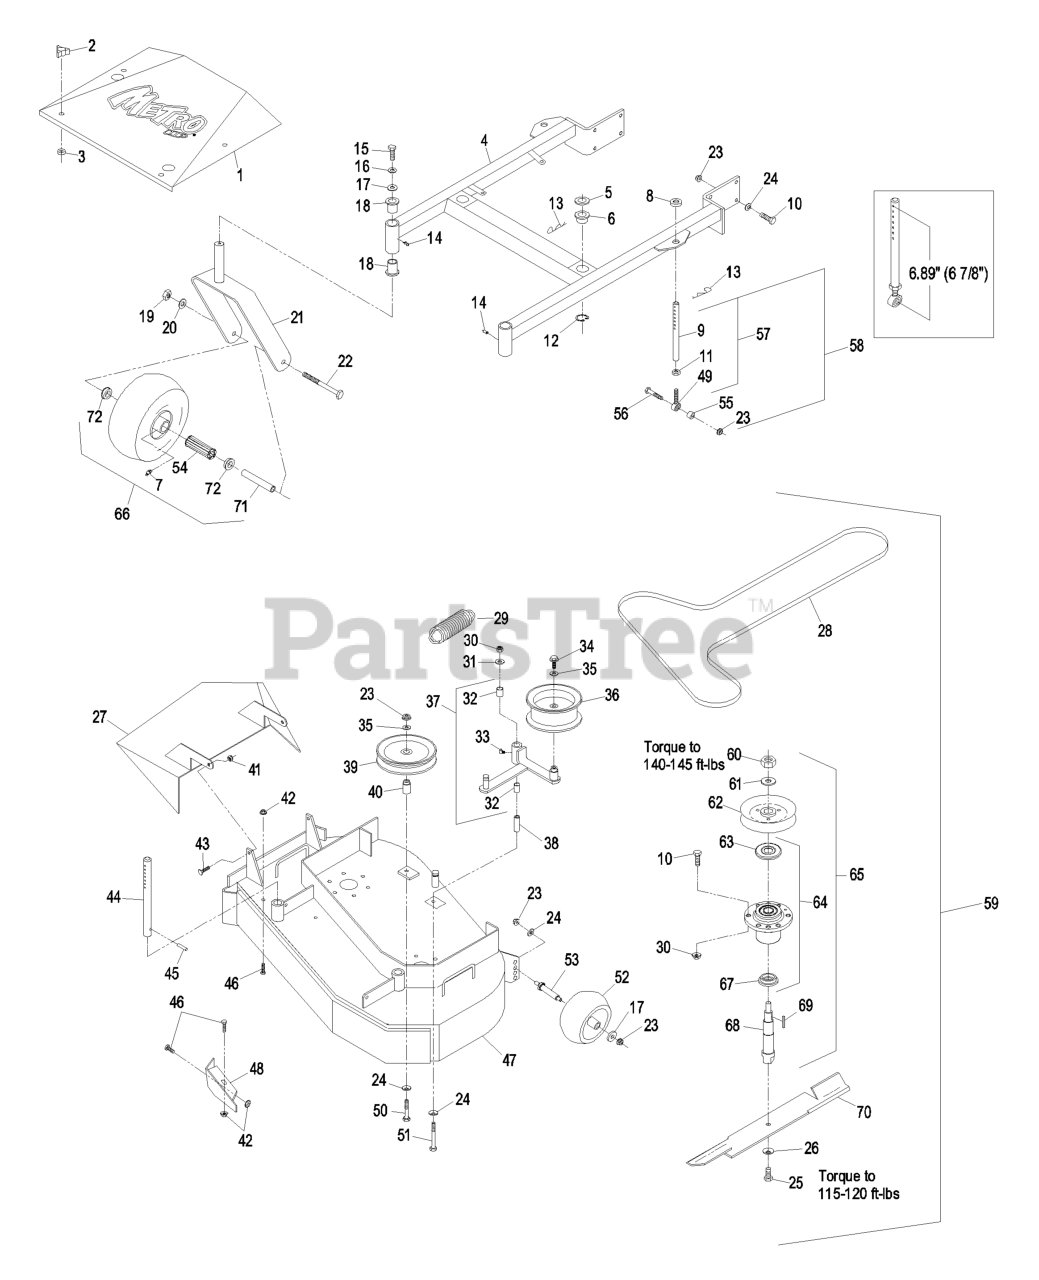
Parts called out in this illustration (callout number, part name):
2	KNOB-3 PRONG
4	DECK SUPPORT W/BSHGS 36"
5	SPACER-DECK SUPPORT
6	BUSHING-DECK
7	FITTING-GREASE
9	LINK,SUPPORT
10	SCREW-HH
11	NUT-HEX
12	RING-RETAINING
13	PIN,HAIR COTTER
14	FITTING-GREASE
15	SCREW-HH
16	WASHER-LOCK
18	BEARING-FLANGED
19	NUT-HH
20	WASHER-LOCK
22	SCREW-HH
23	NUT-HHF, WHIZ
24	WASHER-BELLEVILLE
25	SCREW-CAP
26	WASHER-SPRING
27	WLD,DISCHARGE CHUTE 36/48
28	BELT,DECK DRIVE
30	NUT-LOCK, NI
31	WASHER-FLAT
32	SLEEVE-BEARING
33	FITTING-GREASE, 90 DEG
34	SCREW-HHF
35	WASHER-FLAT
38	BUSHING-PIVOT, IDLER
39	PULLEY-IDLER
40	BUSHING-IDLER
41	NUT-LOCK, NI
43	SCREW-HH
44	ROD,DECK SUPPORT
46	SCREW-HH
47	ASM,DECK W/DECALS TTHP/MH
49	BALLJOINT
50	SCREW-HH
51	SCREW-HH
52	ROLLER-SCALP, ANTI
54	BEARING
56	SCREW-HH
59	Asm, Deck Complete
62	SHEAVE,W/HUB 5.72
63	GUARD-BEARING, TOP
66	KIT, SP CASTER WHEEL REPL
67	SPACER-GUARD, BOTTOM
68	SPINDLE,SHAFT
69	KEY-RECTANGLE
71	SPACER FRONT CASTER
72	BUSHING, SP CASTER
